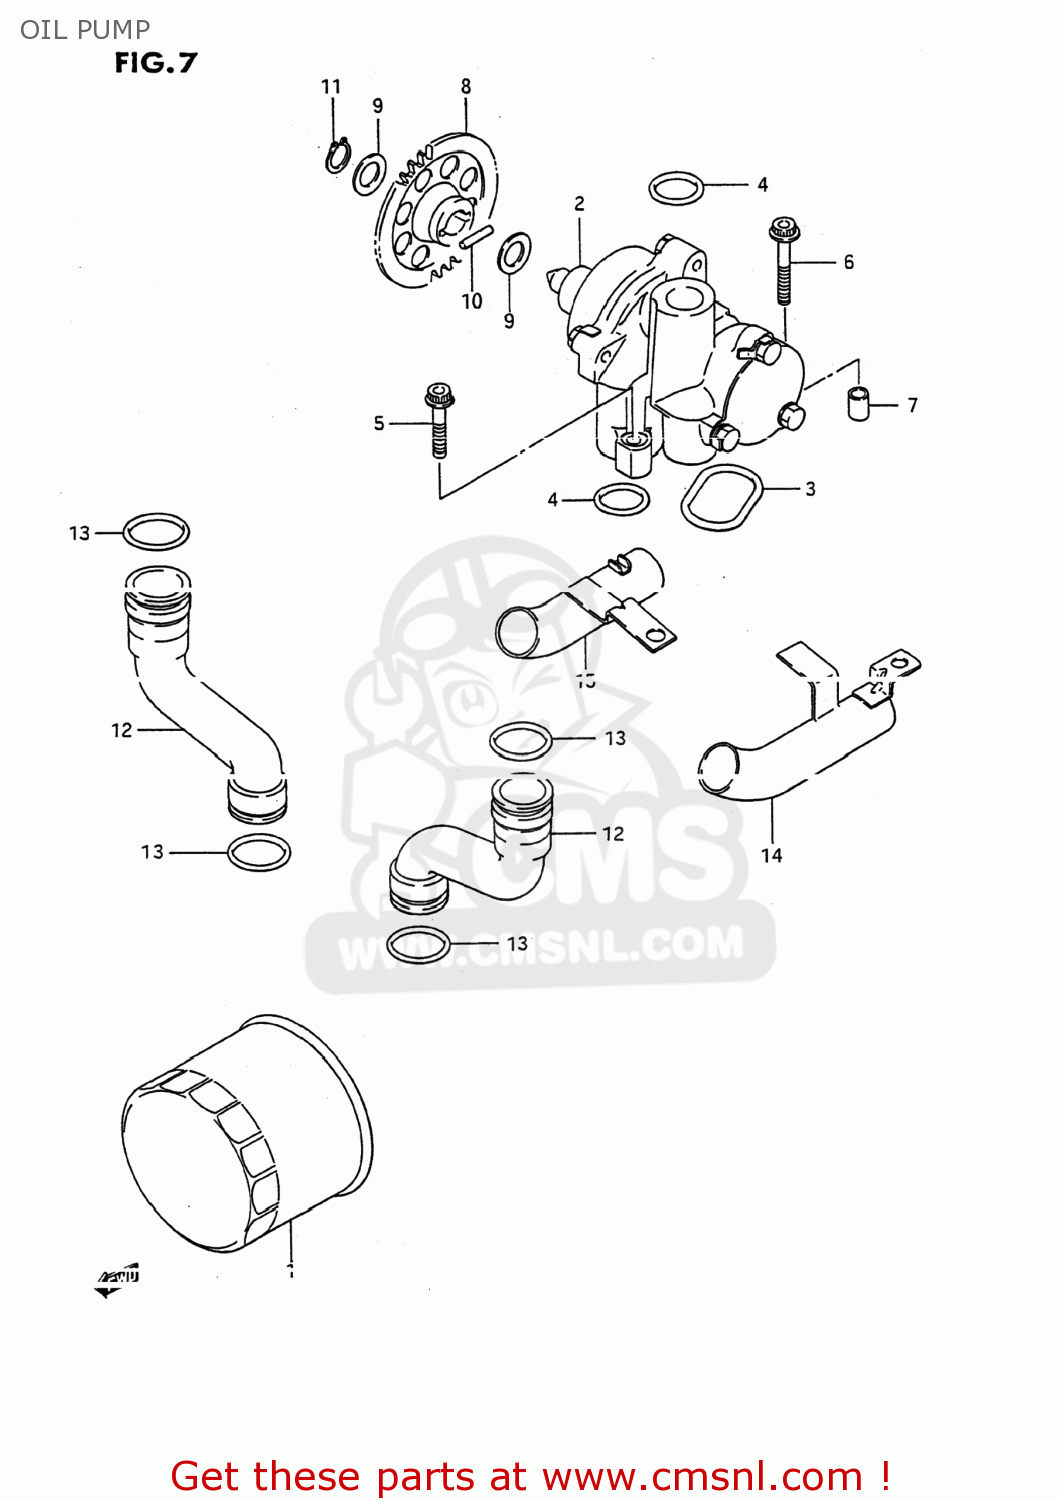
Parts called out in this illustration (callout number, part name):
1	FILTER ASSEMBLY,ENGINE OIL
2	PUMP ASSY,OIL
3	O RING,OIL PUMP
4	O RING(D:3.2,ID:17.8)
5	BOLT
6	BOLT
7	PIN
8	GEAR,OIL PUMP DRIVEN(NT:37)
9	SHIM
10	PIN(5X18)
11	CIRCLIP,12 MM
12	PIPE,OIL OUTLET
13	O RING(D:3.7,ID:21.7)
14	PIPE,OIL,OUTLET,UNDER
15	PIPE,OIL OUTLET UNDER,R
